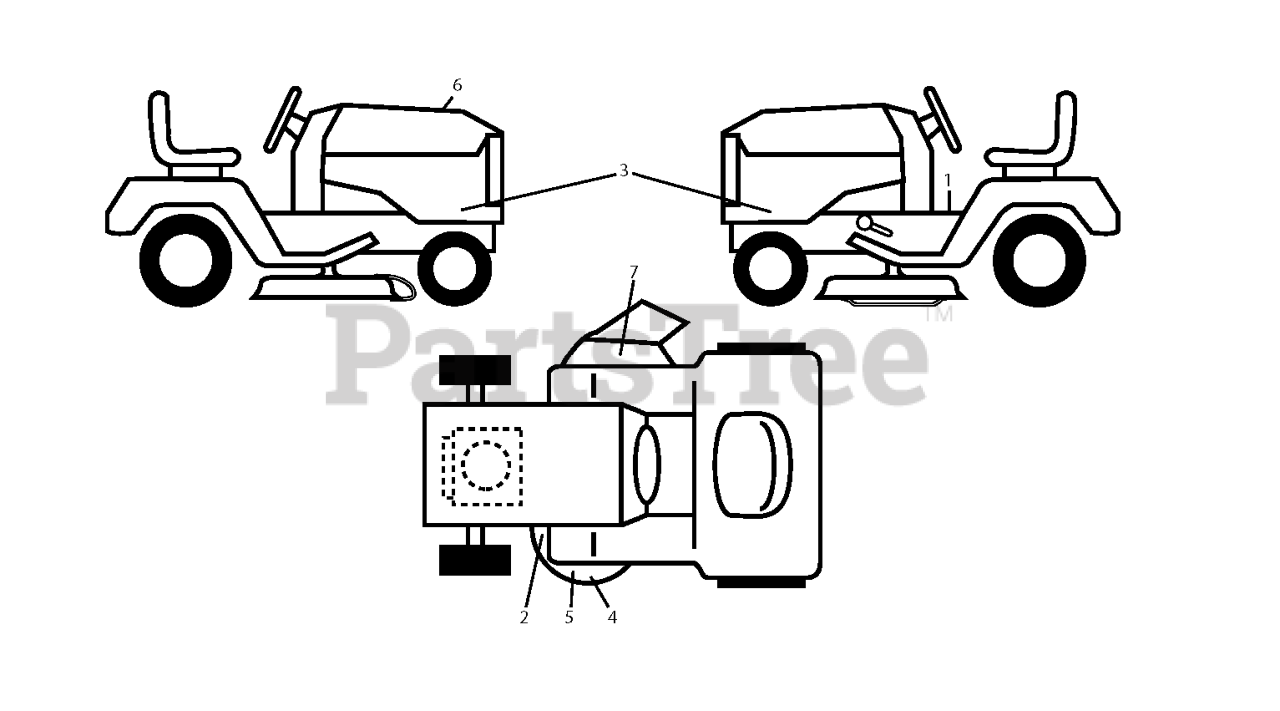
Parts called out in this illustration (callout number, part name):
1	DECAL.WARNING.2007.ENG/FR
1	DECAL.FENDER.WARNING.ENGLISH
2	DECAL.DECK.BELT.ROUTING.48/54
3	DECAL.SDPNL.HUSQGT.TS148XK.SET
5	DECAL.DECK.STAMP.BIOCLIPCMP.HU
7	DECAL.DECK.DEFLECTOR.WARNING
